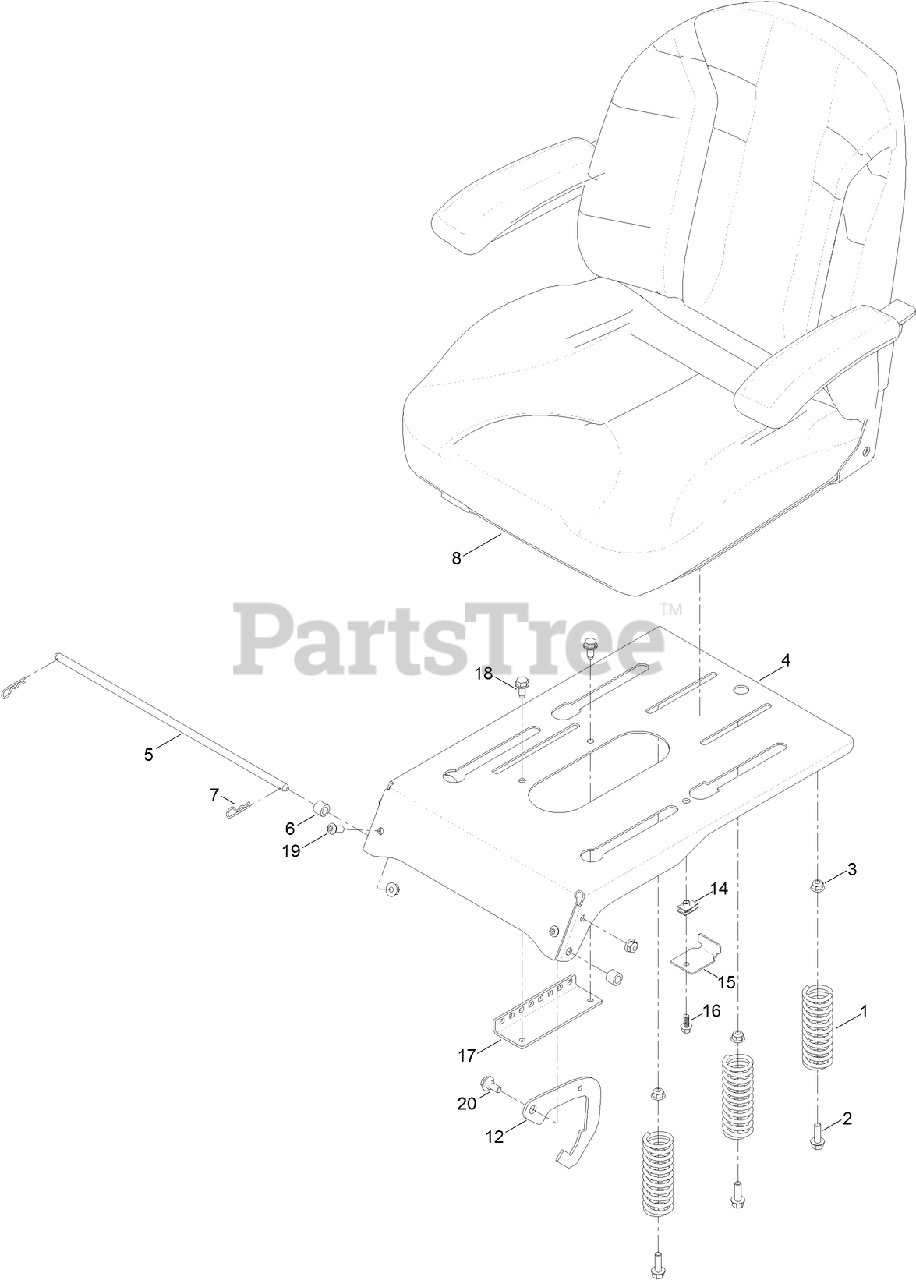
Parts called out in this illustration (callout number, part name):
1	SPRING-COMPRESSION
2	SCREW-HHF
3	NUT-HF, NI
4	PAN-SEAT, DELUXE
5	ROD-STOP
6	BUSHING-LEVER, LIFT
7	PIN-COTTER
8	SEAT ASM
12	LATCH-SEAT
15	BRACKET-STOP, SEAT
16	SCREW-HHF
17	BRACKET-LATCH, SEAT
18	SCREW-HWHTF
19	SCREW-HSBH
20	SCREW-SHOULDER
